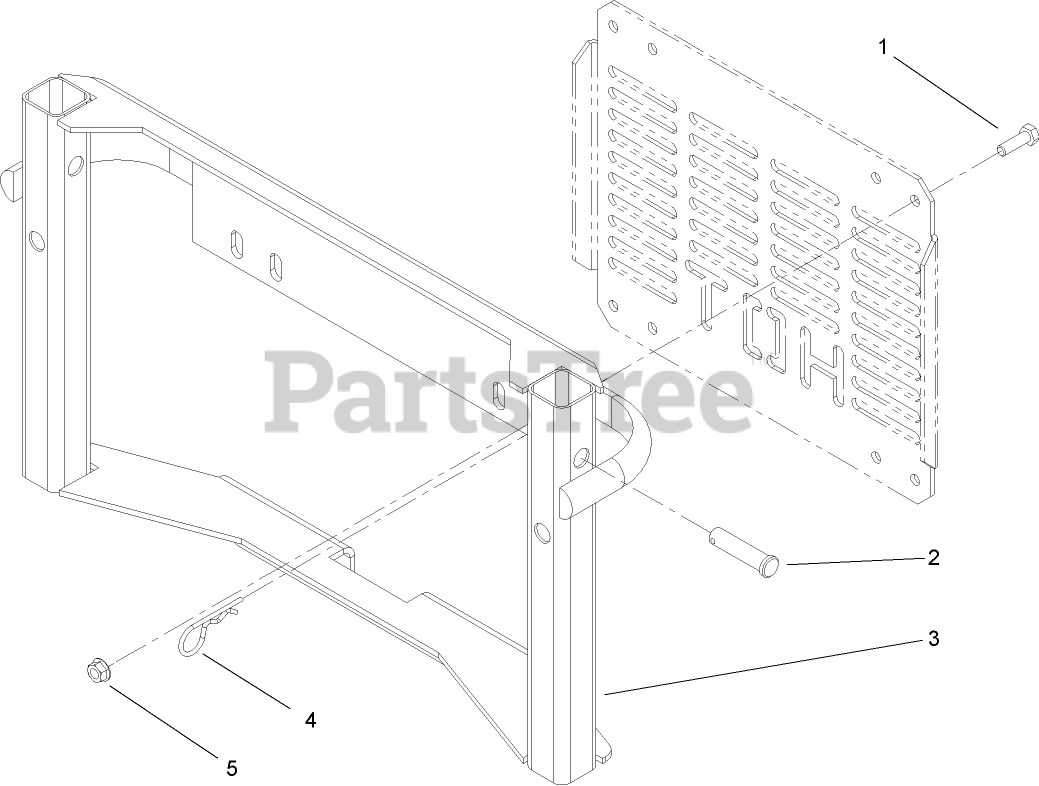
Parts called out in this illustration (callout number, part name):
1	SCREW-HH
2	PIN-CLEVIS
3	BAGGER MOUNT ASM
4	PIN-COTTER
5	NUT-HF
